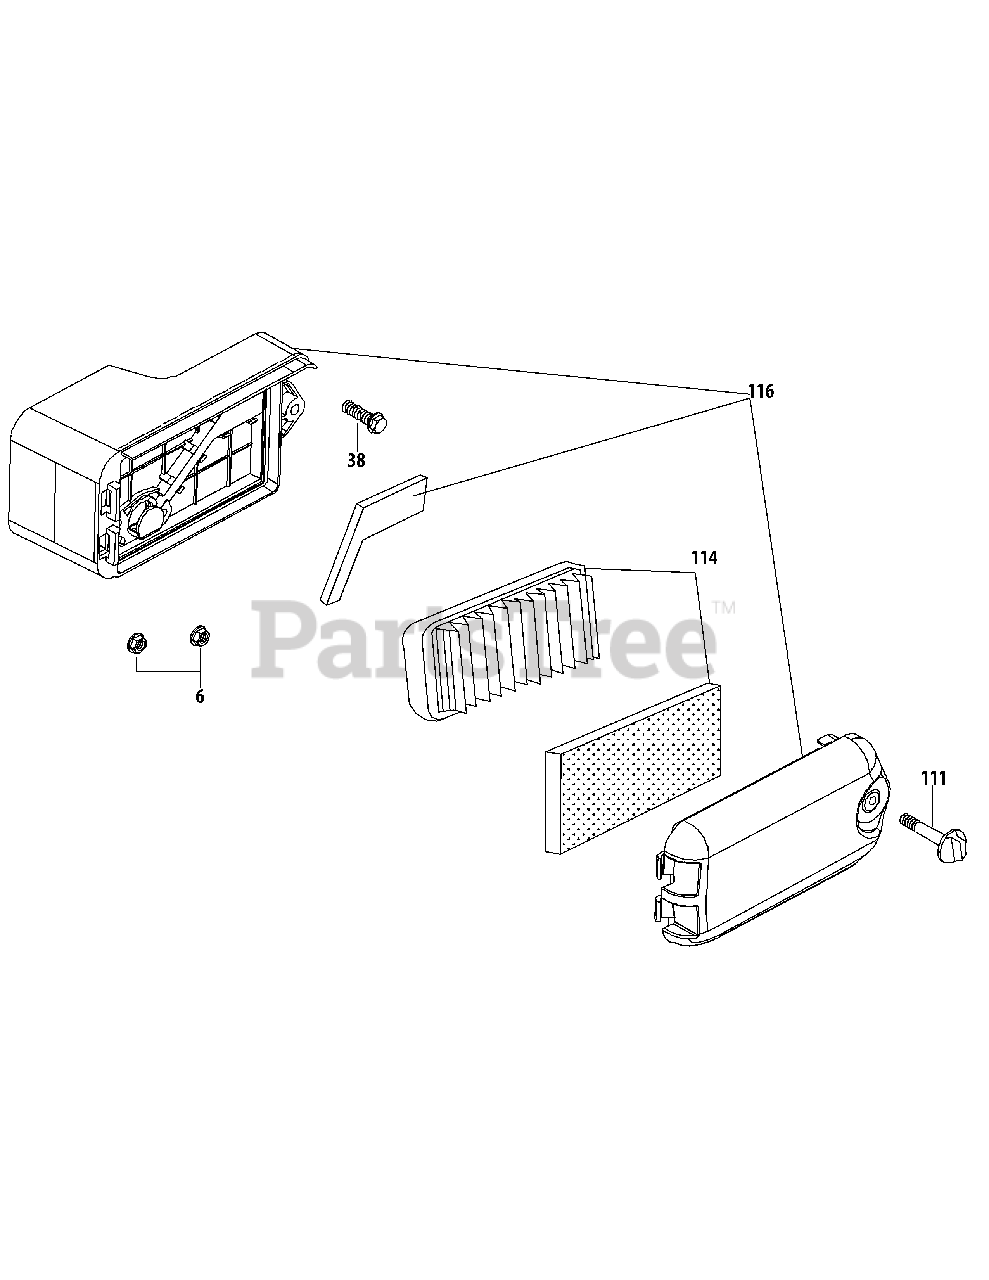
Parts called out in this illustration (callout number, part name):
6	Nut M6X10Mm
38	Bolt M6X35
111	Air Filter Cover Thumb Screw
114	Air Filter/Cleaner Kit
116	Air Cleaner Housing Ass'y Comp
